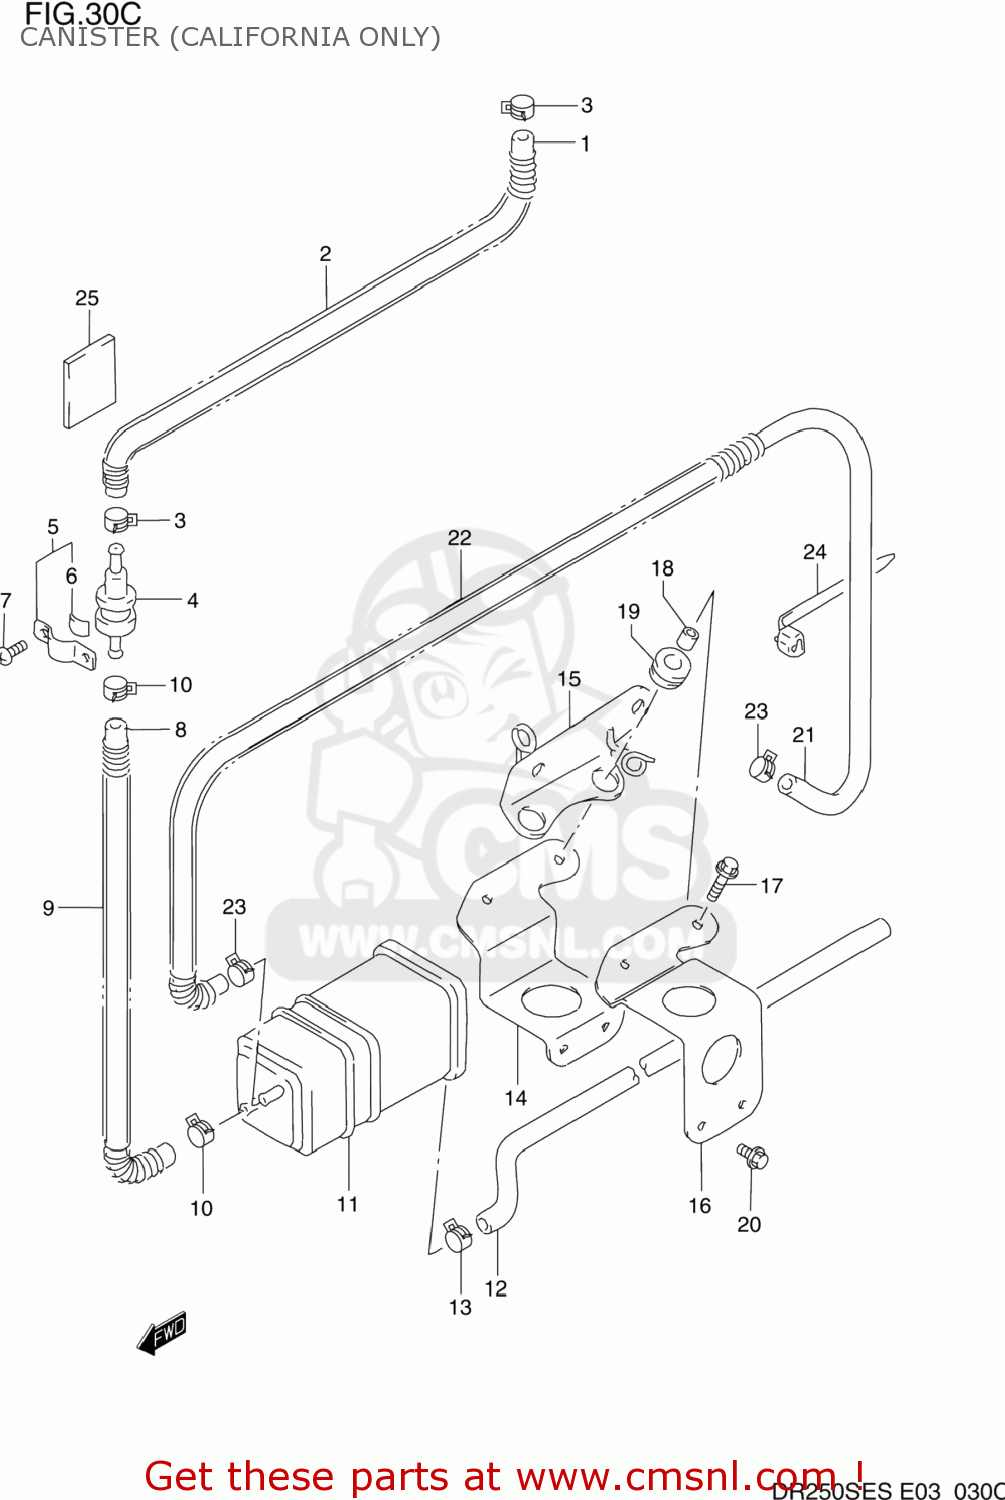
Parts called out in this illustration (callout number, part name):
1	HOSE (5.4X11.4X790)
2	SPRING
3	CLIP
4	VALVE,FUEL TANK BREATHER
5	PLATE,FUEL TANK BREATHER NO.2
6	CUSHION
7	SCREW
8	HOSE(5.4X11.4X350)
9	SPRING
10	CLIP
11	CANISTER ASSY,CHARCOAL
12	HOSE,CANISTER PURGE AIR
13	CLIP
14	PLATE COMP,CANISTER,LOWER
15	PLATE COMP,CANISTER
16	PLATE,CANISTER,UPPER
17	BOLT(6X23)
18	SPACER (6,8X10X9.4)
19	CUSHION
20	BOLT
21	HOSE (5.4X11.4X790)
22	SPRING
23	CLIP
24	CLAMP
25	CUSHION
